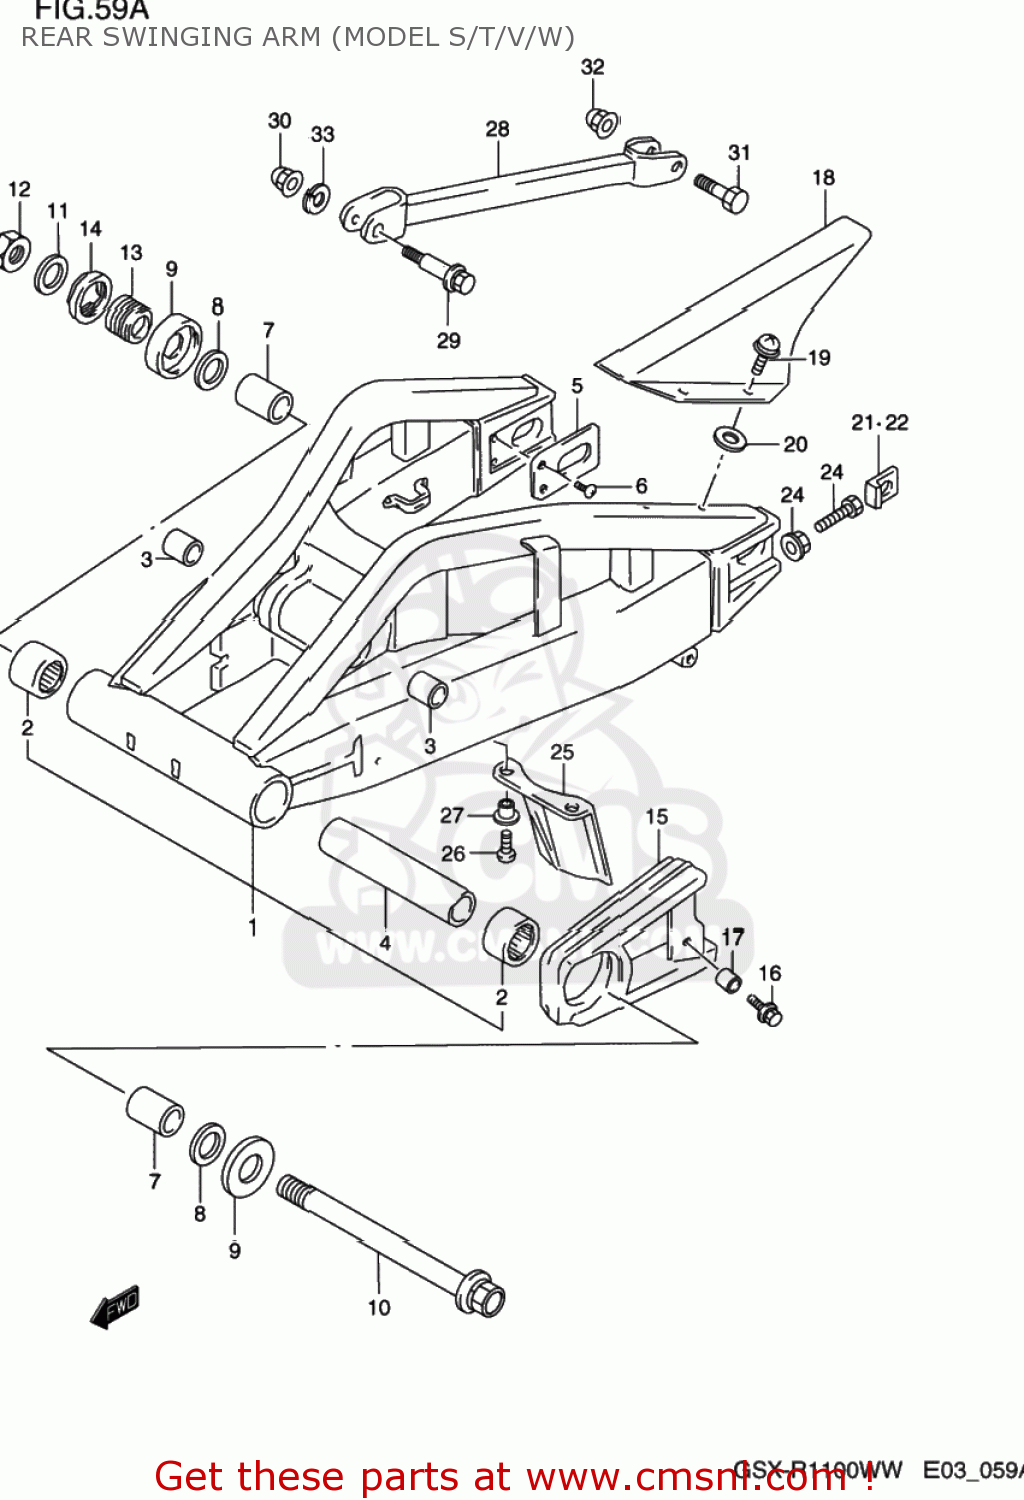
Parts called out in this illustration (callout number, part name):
1	SWING ARM ASSEMBLY,REAR
2	BEARING(30X40X25)
3	BEARING(17X24X20)
4	SPACER (25.4X31.8X157.9)
5	PLATE,RR SWING ARM BRKT
6	SCREW 6X10
7	SPACER,REAR SWING ARM PIVOT
8	WASHER
9	DUST SEAL,RR SWGARM PIVOT
10	SHAFT,REAR SWING ARM PIVOT
11	WASHER(25.2X42X3.2)
12	NUT
13	BOLT,REAR SWING ARM PIVOT
14	NUT,REAR SWING ARM PIVOT BOLT
15	BUFFER,CHAIN TOUCH DEFENSE
16	BOLT 6X20,WITH PLAIN WASHER
17	SPACER(6.5X10X7)
18	CASE,CHAIN
19	SCREW(6X20)
20	WASHER(6.5X18X1.6)
21	WASHER,CHAIN ADJUSTER
22	WASHER,CHAIN ADJUSTER
23	BOLT(8X50)
24	NUT
25	GUARD,RR UNIT MUD
26	SCREW
27	WASHER
28	TORQUELINK,RR
29	BOLT
30	NUT
31	BOLT(10X37)
32	NUT
33	LOCK WASHER
